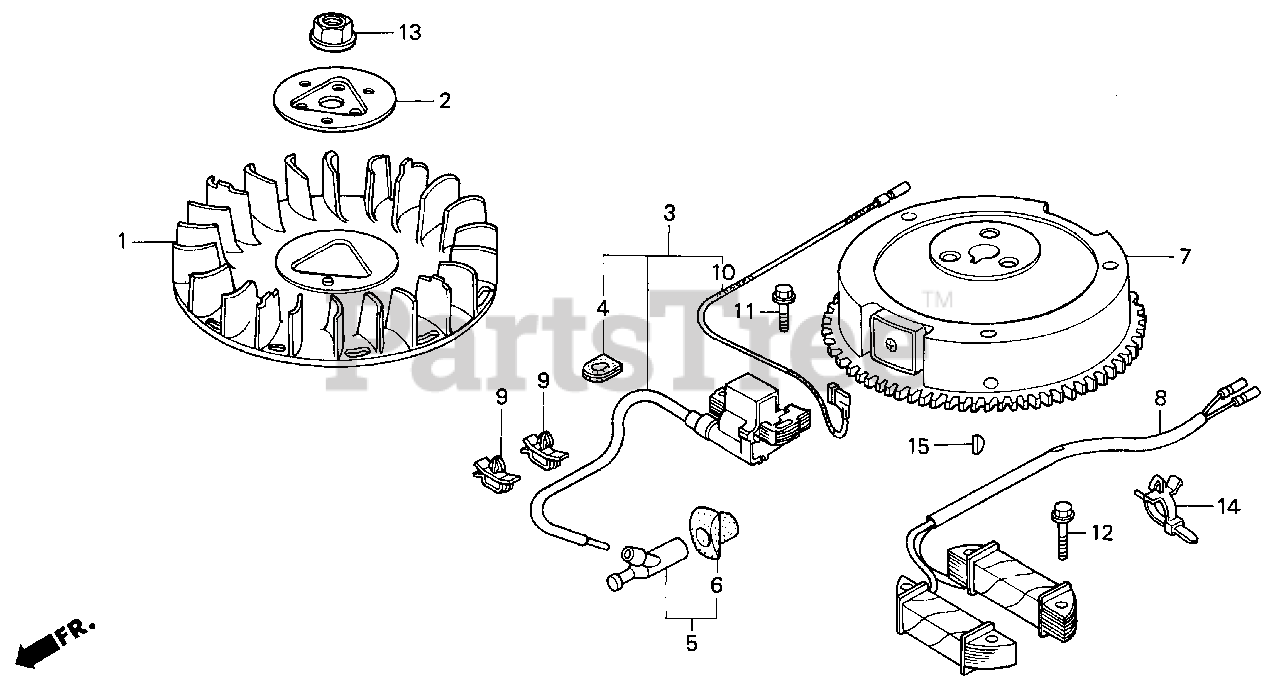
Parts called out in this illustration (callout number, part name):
1	FAN, COOLING
2	PLATE, COOLING FAN SETTING
3	COIL ASSY., IGNITION
4	GROMMET, IGNITION
5	TERMINAL ASSY., IGNITION
6	SEAL, IGNITION TERMINAL
8	COIL ASSY., CHARGE (10A)
9	CLIP, WIRE HARNESS
10	WIRE, STOP SWITCH
11	BOLT, FLANGE (6X28)
12	BOLT, FLANGE (6X32)
13	NUT, SPECIAL (16MM) (1)
13	NUT, SPECIAL (16MM)
14	BAND, WIRE HARNESS (WHITE)
14	CLIP, WIRE HARNESS
15	KEY, SPECIAL WOODRUFF (25X18)
